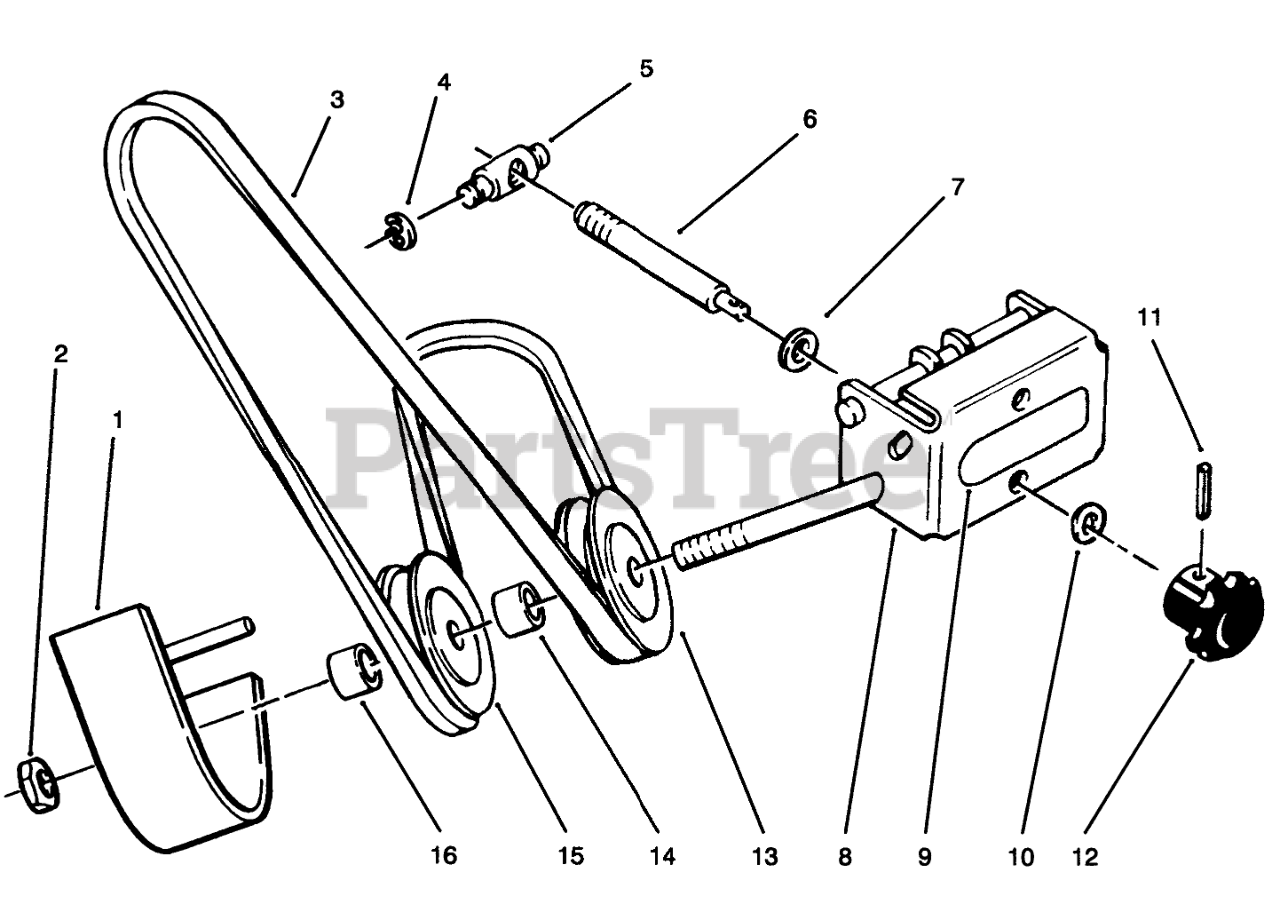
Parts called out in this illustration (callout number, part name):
1	Belt Cover
2	Nut
3	V-BELT
4	RING-RETAINING
5	TRUNNION-DOUBLE
6	ROD ADJ
7	WASHER-FLAT
8	Front Support
9	DECAL-ATTACH A-MATIC
10	WASHER-SPRING
11	PIN-ROLL
12	KNOB-ADJUSTMENT
13	PULLEY-IDLER
14	SPACER
15	PULLEY-FLAT IDLER
16	SPACER-OUTER
